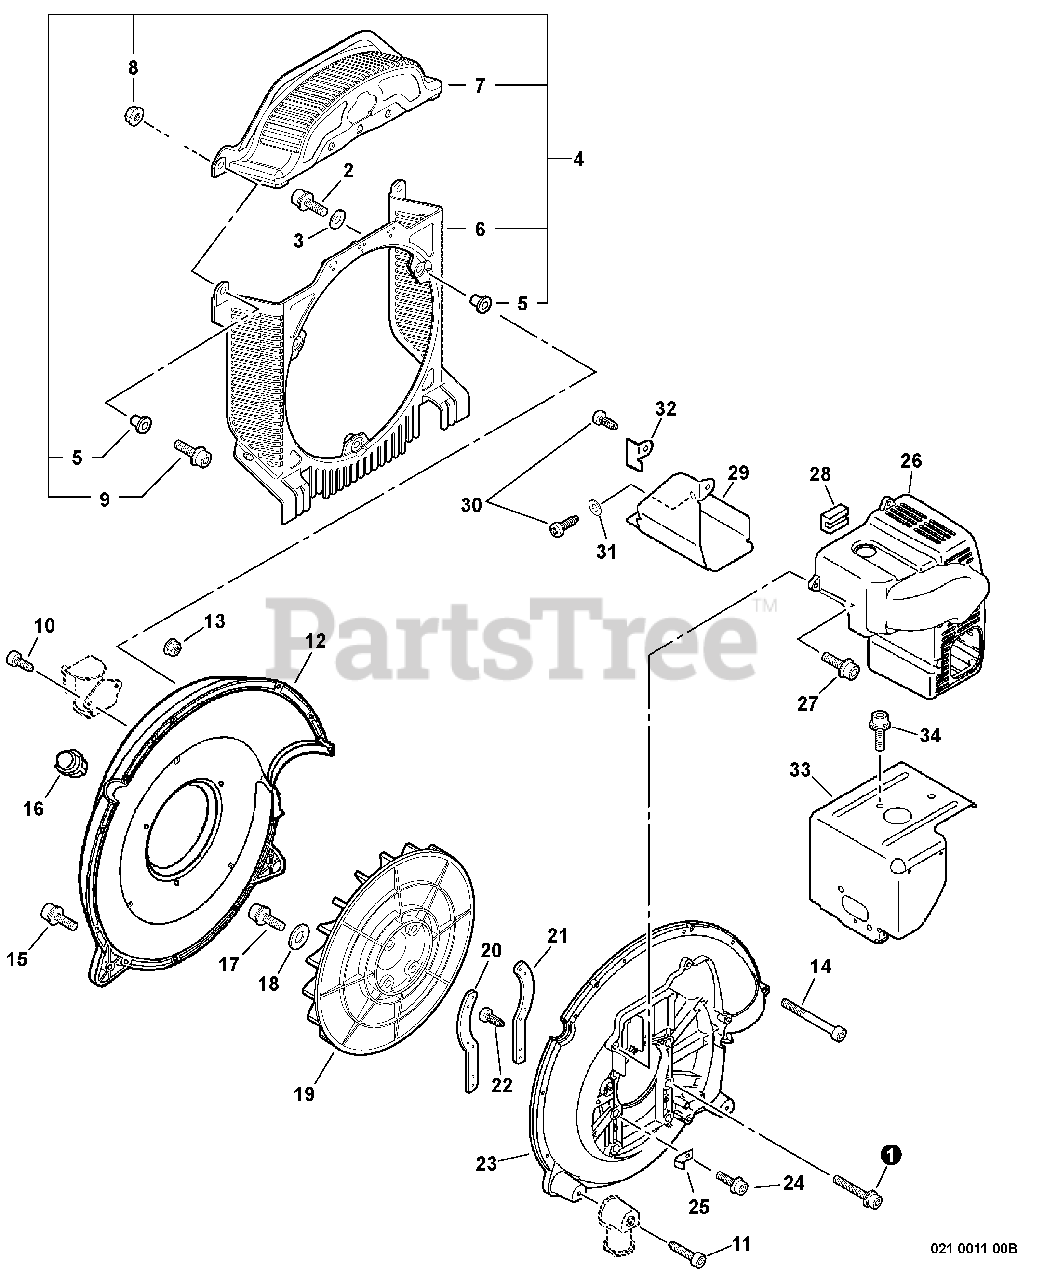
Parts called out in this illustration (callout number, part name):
1	SCREW - 6X35
2	SCREW - 5X20 -- TAPPING
3	WASHER - 5
4	DEBRIS GUARD KIT
6	GUARD, DEBRIS - LOWER
7	GUARD, DEBRIS - UPPER
8	LOCKNUT - 5
9	SCREW - 5X20
10	SCREW - 5X16
11	SCREW - 5X16
12	COVER, FAN - INNER
13	NUT - 5 -- FLANGE
14	SCREW - 5X60
15	SCREW - 5X20 -- TAPPING
17	SCREW - 6X35
18	WASHER - 6
20	PLATE - LEFT
21	PLATE - RIGHT
22	SCREW - 5X14
23	COVER, FAN - OUTER
24	SCREW - 5X16
26	COVER, ENGINE
27	SCREW - 5X20 -- TAPPING
28	CUSHION
29	SHIELD, EXHAUST
30	SCREW - 5X10
31	WASHER - 5
32	BRACKET, SHIELD
33	SHIELD, CYLINDER - INTAKE
34	SCREW - 5X8
